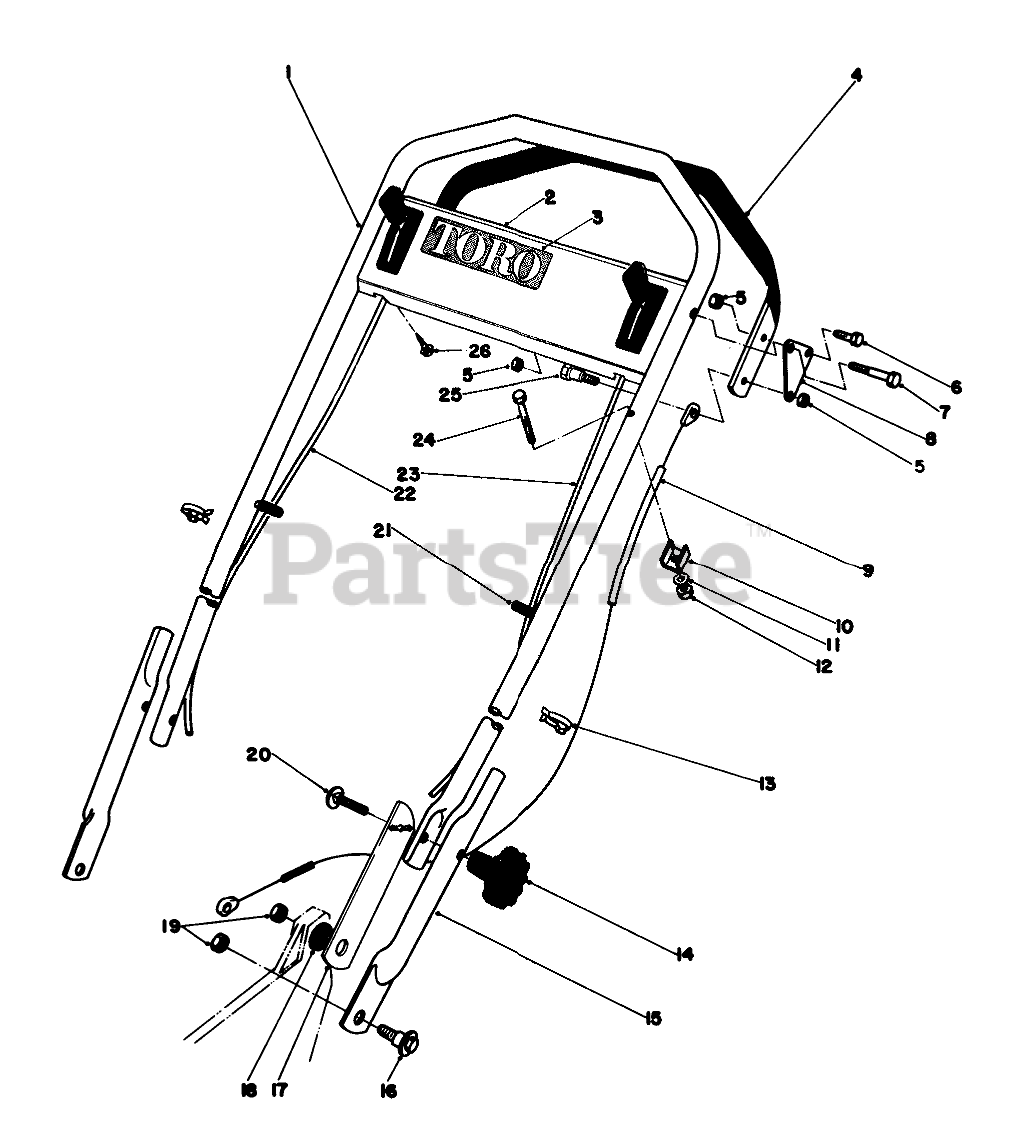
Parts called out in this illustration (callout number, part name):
1	Upper Handle
2	Control Plate (Incl. Ref. #3)
3	Decal-Toro
4	DEMAND HANDLE ASM
5	NUT-LOCK, CONE
6	SCREW-HH
7	BOLT-SHOULDER
8	Bracket Demand
9	DEMAND HAND CABLE
10	CLAMP-CABLE
11	WASHER-FLAT
12	NUT-LOCK, NI
13	BOWDEN CLIP
15	LOWER HANDLE
16	SCREW-SHOULDER
17	HANDLE LATCH
18	HANDLE LATCH SPACER
19	Nut
20	SCREW-CARR
21	CAP-VINYL
22	Ground Speed Control
23	Throttle Control
24	SCREW-HH
25	SHOULDER BOLT
26	SCREW-HWHTF
